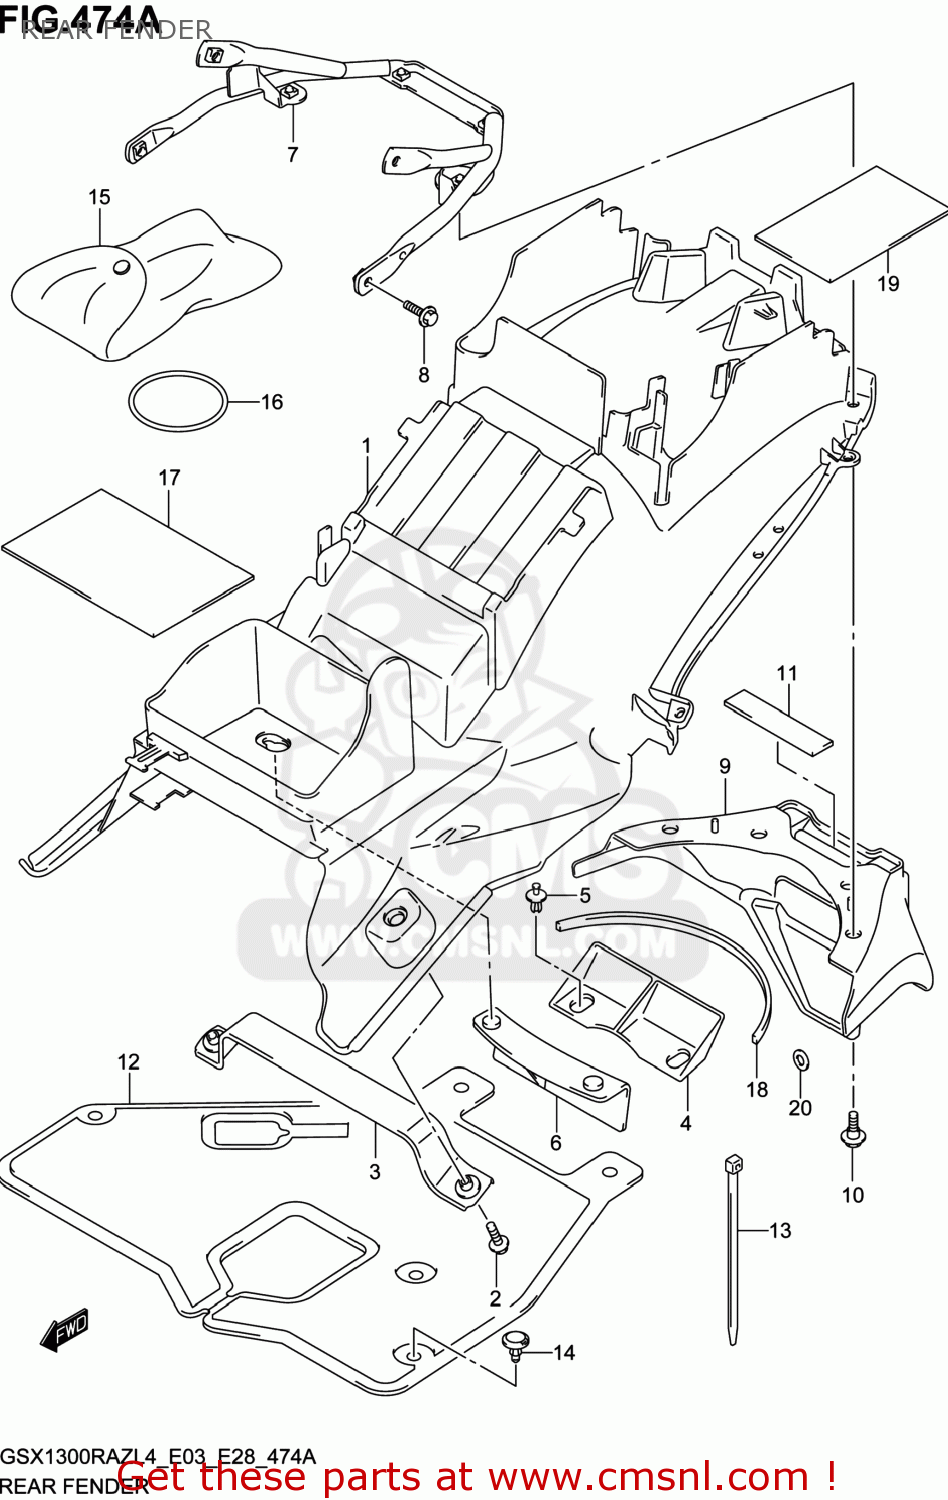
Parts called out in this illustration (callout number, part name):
1	FENDER,RR FR
2	BOLT
3	BRACKET,RR FENDER FR
4	MUDGUARD,RR FENDER
5	CLIP
6	MUDGUARD,RR FENDER FR UPR
7	BRACKET,RR FENDER
8	BOLT
9	FENDER,RR RR
10	BOLT(6X16)
11	PROTECTOR(20X90)X4
12	SHIELD,INNER
13	CLAMP(L:95)
14	CLIP
15	TOOL ASSY
16	O RING(D:3.5,ID:56.5)
17	CUSHION,RR FENDER FR
18	CUSHION,RR FENDER RR
19	CUSHION,TOOL BAG
20	WASHER
